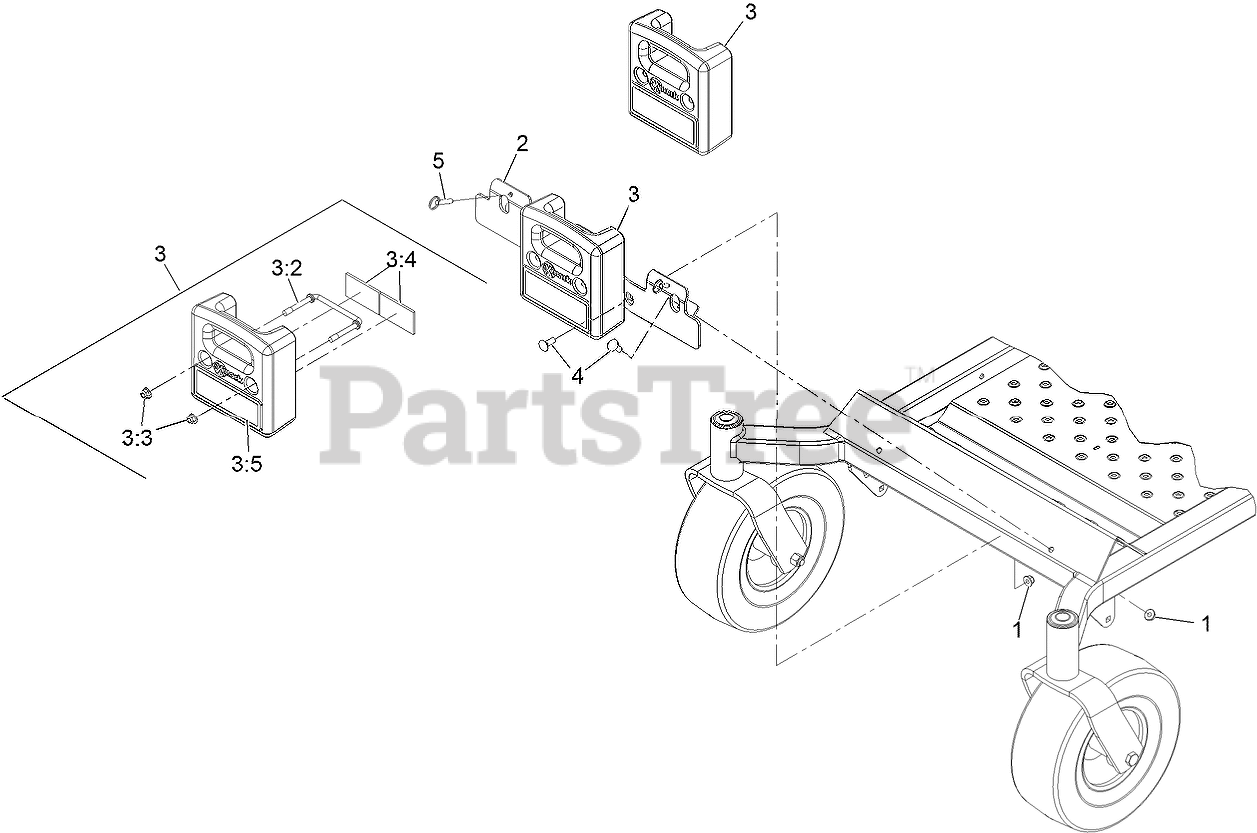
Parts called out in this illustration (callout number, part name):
1	NUT-HF, NI
2	THREE WEIGHT ASM
3	WEIGHT ASM
3:2	WIREFORM-WEIGHT
3:3	NUT-HF, NI
3:4	CUSHION-RUBBER
3:5	DECAL-WARNING WEIGHT
4	BOLT-CARR
5	PIN-BALL, DETENT
